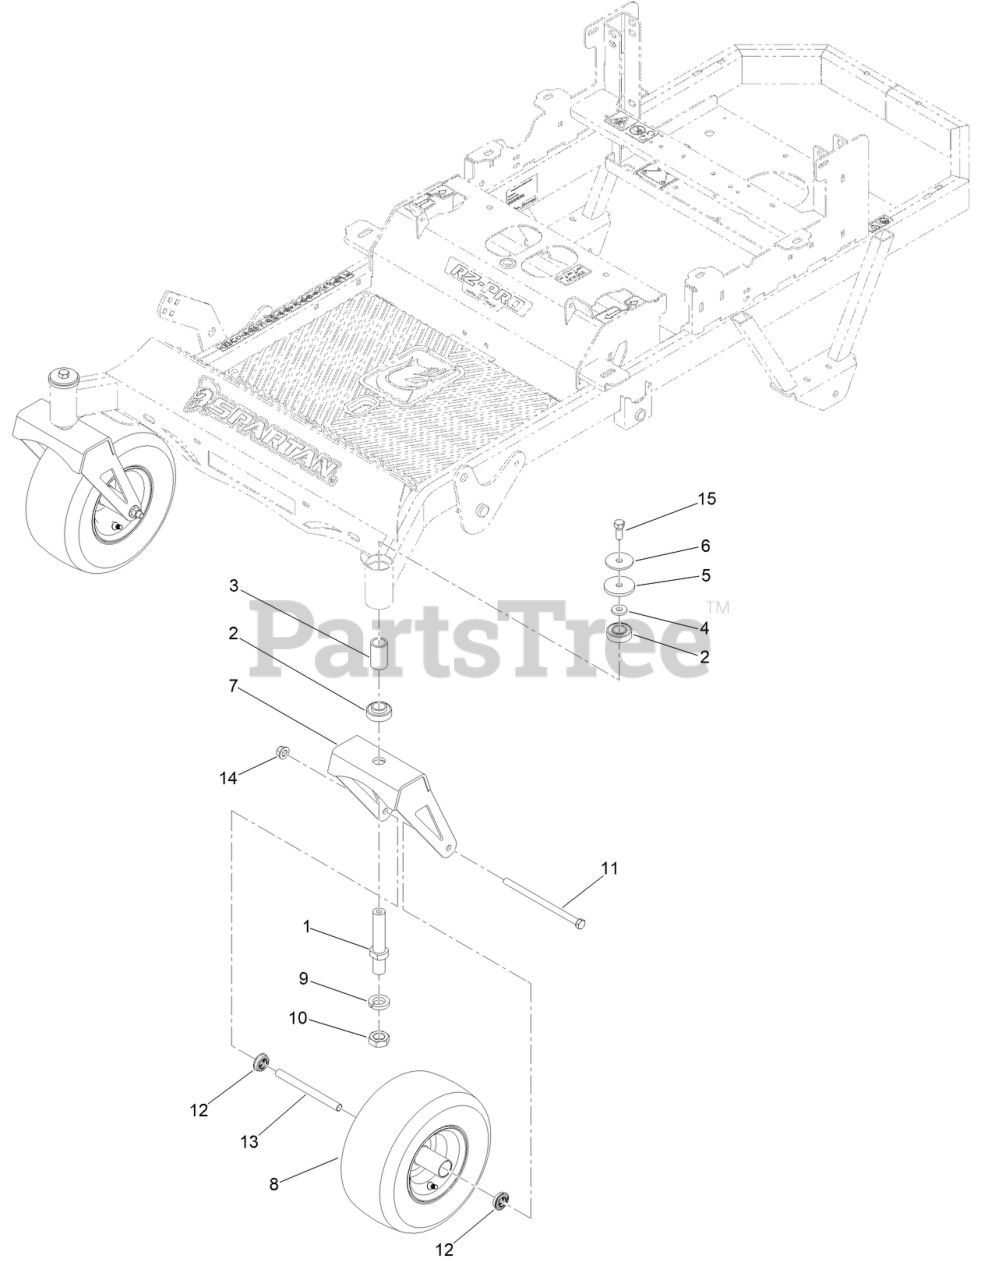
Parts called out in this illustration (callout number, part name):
1	MWR CASTER SHAFT
2	BEARING-BALL
3	CASTER FORK SHAFT BEARING SPACER
4	1/2 FENDER WASHER 1-1/4IN OD ZINC
5	FT HUB PLASTIC WASHER
6	MWR CASTER SHAFT WASHER
7	RZ CASTER FORK ASM
8	RZ/RT PRO FT TIRE ASSY-SMOOTH TREAD
9	1IN L/W MED SPLIT ZC
11	1/2-13 X 8-1/2 HEX C/S GR 5 ZINC YELLOW
12	RZ FT WHEEL BEARING
13	MWR FT WHEEL SPANNER
14	NUT-LOCK
15	1/2-20 X 1-1/4 HEX FLANGE BOLT GR 8 YZ
